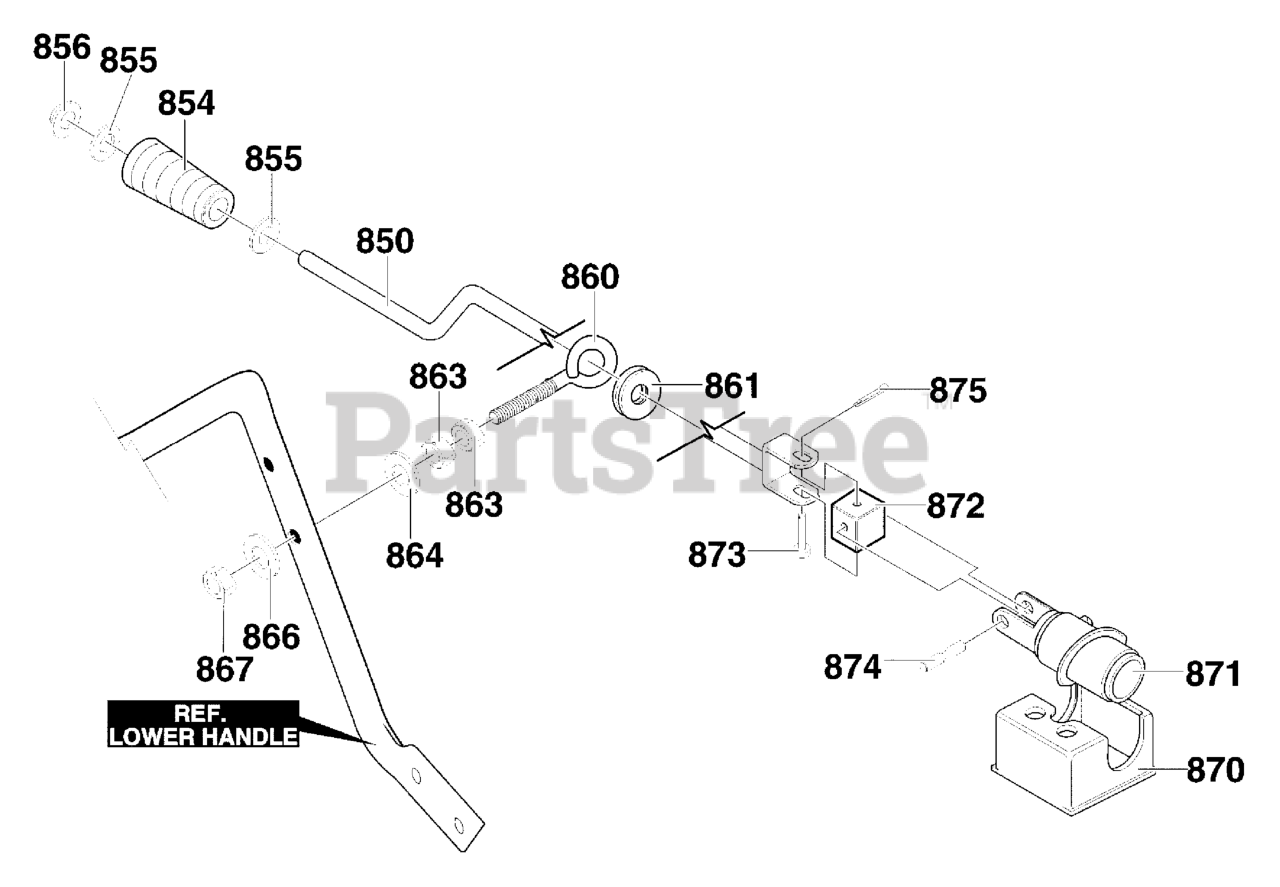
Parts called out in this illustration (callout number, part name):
850	CRANK, ASSY
854	KNOB, SLEEVE
855	WASHER, FLAT .406X .81X.066
856	NUT, PUSH ON 3/8"
860	BOLT, EYE 3/8-16X6.00
861	GROMMET, EYE BOLT
863	NUT, 3/8-16 HEXJAM
864	WASHER, FLAT .406X .81X.066
866	WASHER, FLAT .406X .81X.066
867	NUT, 3/8-16 HEXNYL
870	BRKT, WORM
871	WORM, GEAR CHUTE
872	BLOCK, UNIV PIV
873	PIN, CLEVIS
874	PIN, UNIV JOINT
875	PIN, COTTER
